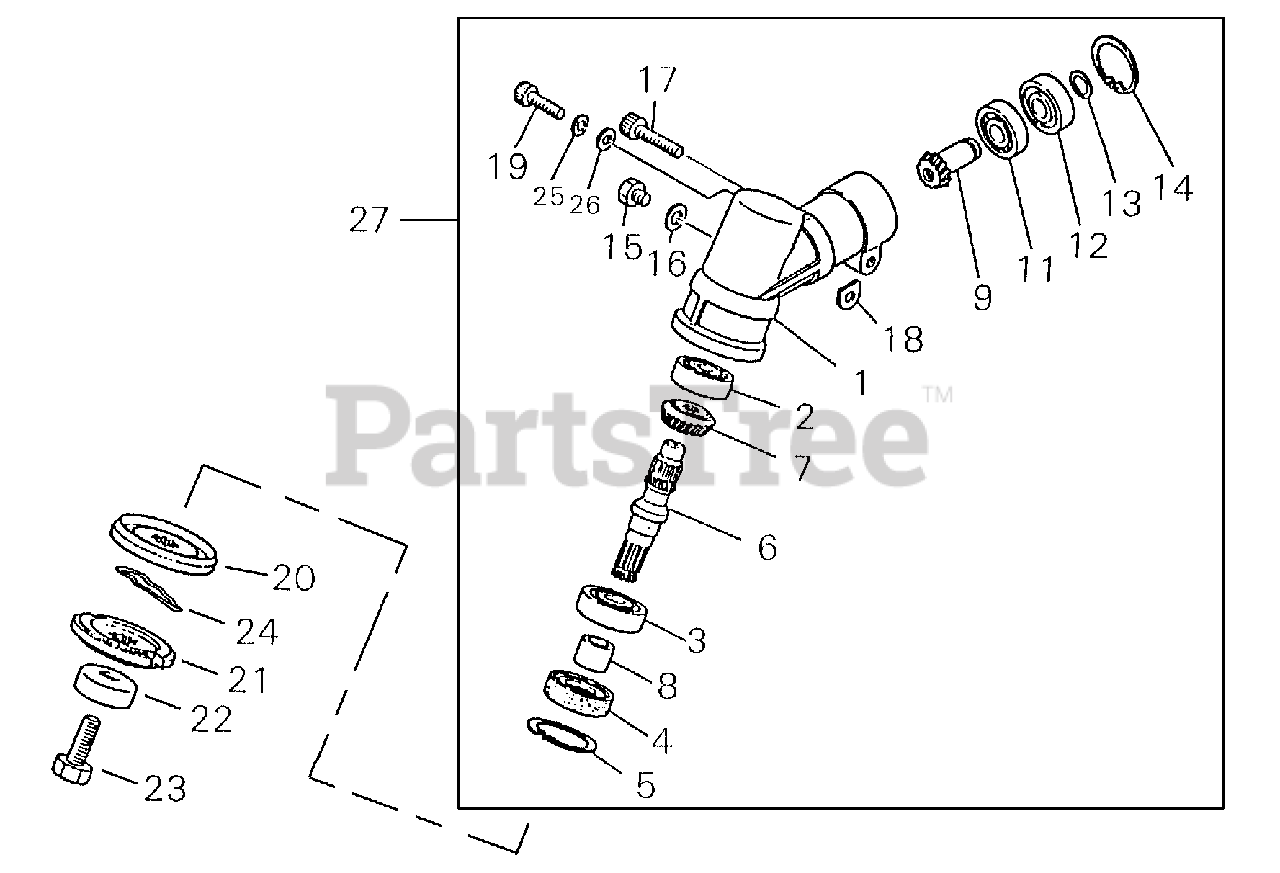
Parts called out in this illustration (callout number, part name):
1	CASE, GEAR
2	BEARING, BALL - 6000DDU
3	BEARING, BALL - 6201
4	SEAL, OIL
5	RING, RETAINING - 32
6	GEAR - SHAFT
7	GEAR - BEVEL
8	COLLAR
9	GEAR SHAFT ASSY
11	BEARING, BALL - 6000
12	BEARING, BALL - 6000
13	RING, RETAINING
14	RING, RETAINING - 26
15	BOLT - 6X10
16	WASHER
17	SCREW - 6X28
18	SHIM
19	SCREW - 5X12
20	HOLDER
21	ADAPTOR, BLADE - LOWER
22	GUARD
23	BOLT - 8 -- LEFT HAND
24	CLIP
25	LOCKWASHER - 5
26	WASHER - 5
27	GEAR CASE ASSY
